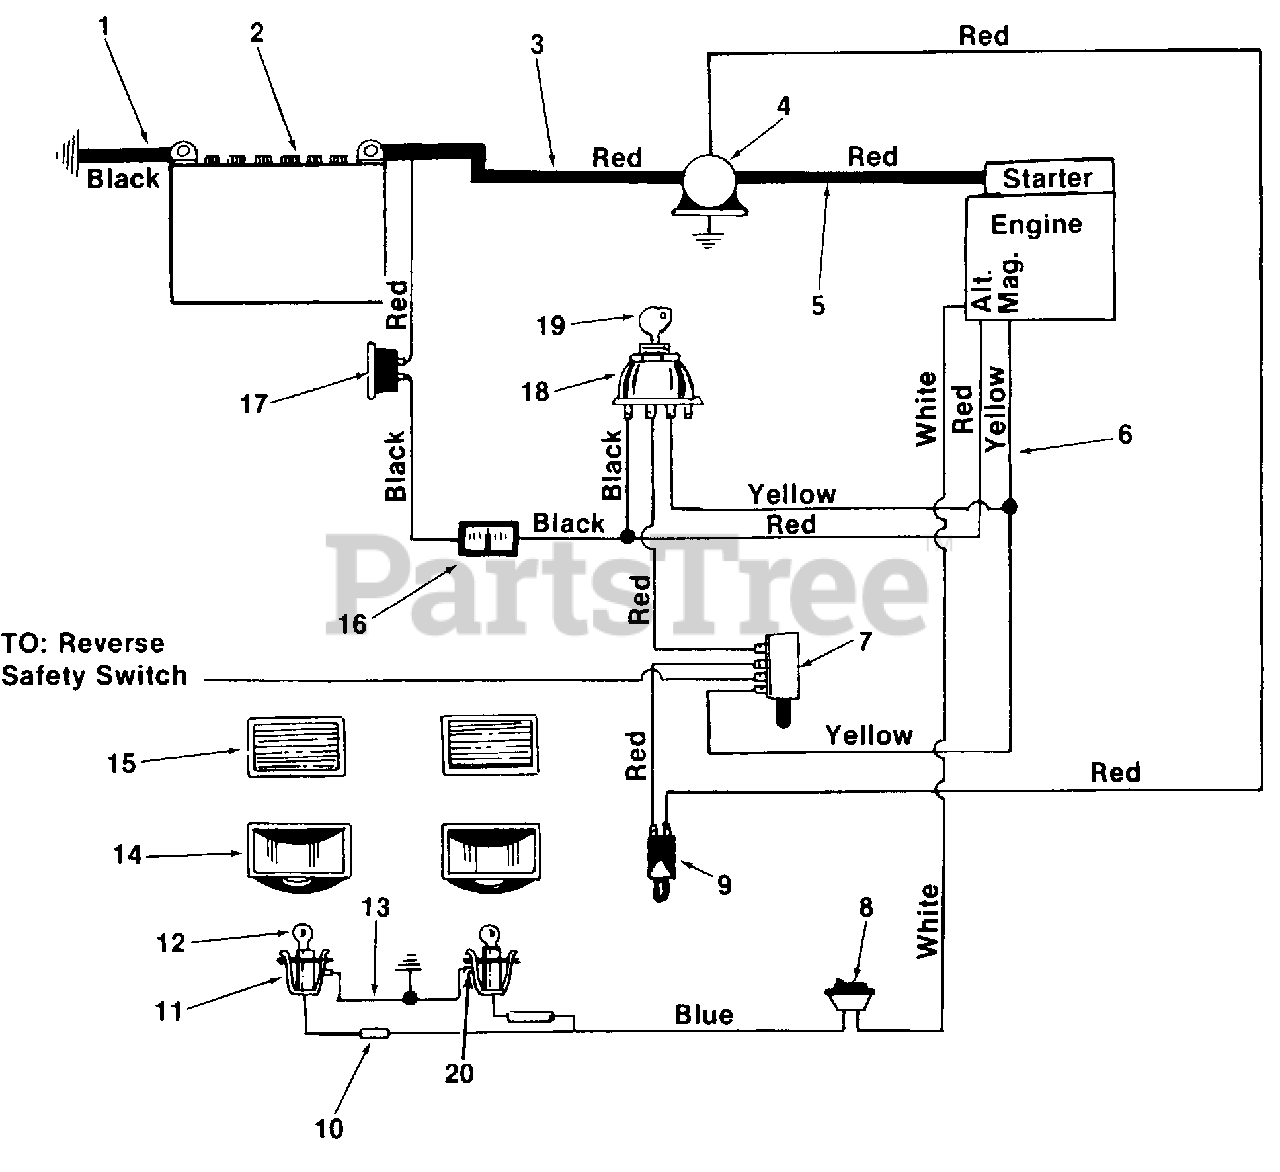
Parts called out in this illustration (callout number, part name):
1	Electric Wire
2	12V-Battery
3	Electric Wire
4	Solenoid
5	Electric Wire
6	Wire Harness
7	Safety Switch
8	Light Switch
9	Safety Switch
10	Tab Receptacle
11	Socket
12	Lamp
13	Ground Wire
14	Head Light Housing
15	Lens
16	Ammeter
17	Circuit Breaker
18	Ignition Switch
19	Ignition Key
20	Push On Ground Clip
